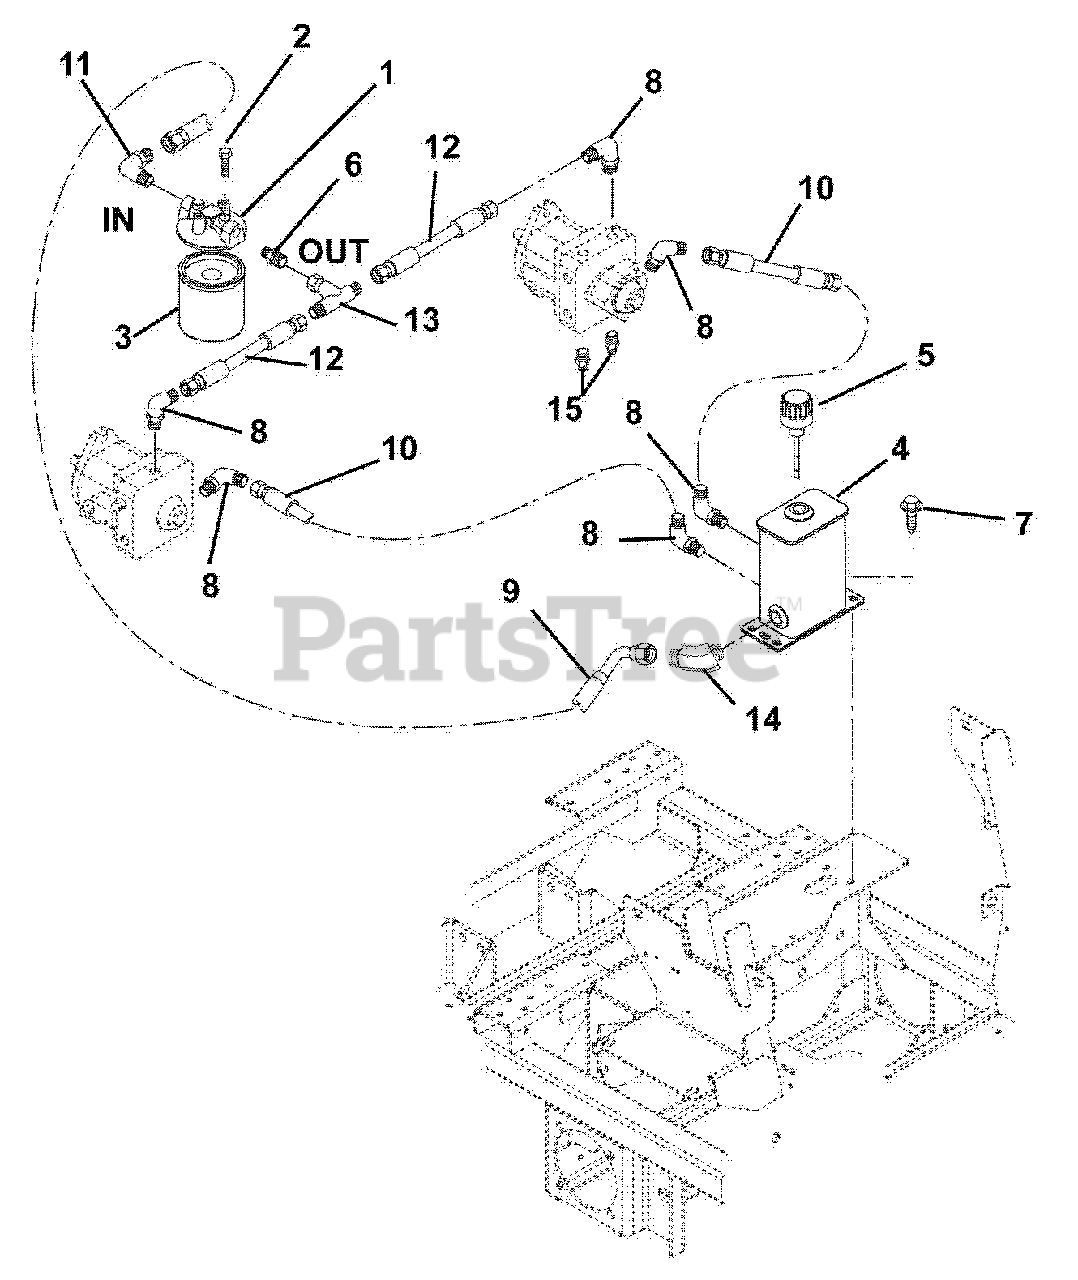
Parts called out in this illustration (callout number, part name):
1	Head, Filter (SN 000101 - 200)
2	Bolt-Hex .25-20 x .50 Grade 5 Epoxy
3	Filter Element
4	Body, Hydraulic Tank (SN 000101 - 002499)
5	Breather, Dipstick
6	Fitting, Hydraulic, Straight (SN 000101 - 200)
7	Screw-Tapping .38-16 x .75 Hex Washer Head
8	Fitting, Hydraulic, 90 Degree Elbow
9	Hose-Hydraulic Valve to Tank
10	Hose, Hydraulic, 10-inch
11	Fitting, Hydraulic, 90 Degree Elbow (SN 000101 - 200)
12	Hose, Hydraulic .50, 5-Inch
13	Fitting, Hydraulic Tee
14	Fitting, Hydraulic .45 Degree Elbow (SN 000101 - 002499)
15	Fitting, Hydraulic (4 F5OLO)
